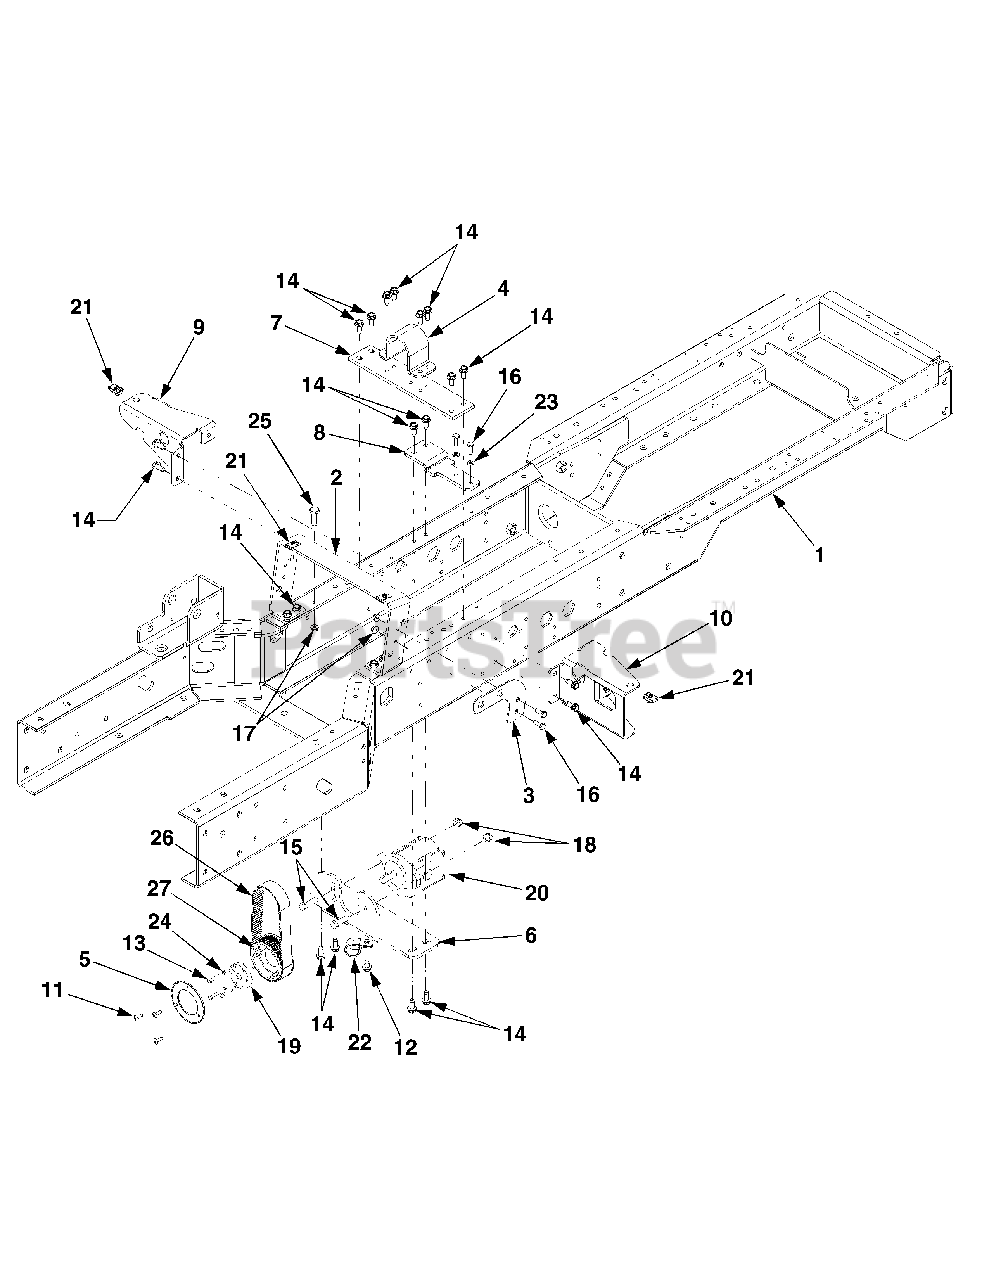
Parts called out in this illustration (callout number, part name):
2	Bracket, Front Seat Mount
3	Bracket, Fitting Mtg.
4	Shield, Drive Shaft
5	Keeper, Belt
6	Bracket, Aux. Pump Mtg.
7	Shield Lower Drive Shaft
8	Plate, Filter Mounting
9	Bracket, Running Board Mtg.
10	Bracket, Running Board Mtg.
11	Screw, Truss Hd. Mach. #10-24 x .5
12	Screw, Hex Wash. Hd Tapp 5/16-18 x .5
13	Screw, Hex Mach. #10-24 x 1.0 GR5
14	Screw, Hex Wash. Hd. Tapp, 5/16-18 x .75
15	Screw, Hex Cap, 3/8-16 x 1.25 GR5
16	Screw, Hex Cap, 1/4-20 x .75 GR5
17	Nut, Hex Nylon Flange Lock, 1/4-20 GRF
18	Nut, Hex Lock, 3/8-20 GrB
19	Bushing, Tapered
20	Pump, Aux. Hydraulic
21	Nut, U Speed, 5/16-18
23	Washer,Lock, 1/4
24	Washer, Lock, #10
25	Screw, Shoulder, .374 x 1.16
26	Belt, HTS, 5 x 25 x 500
27	Pulley, 52T Cog
